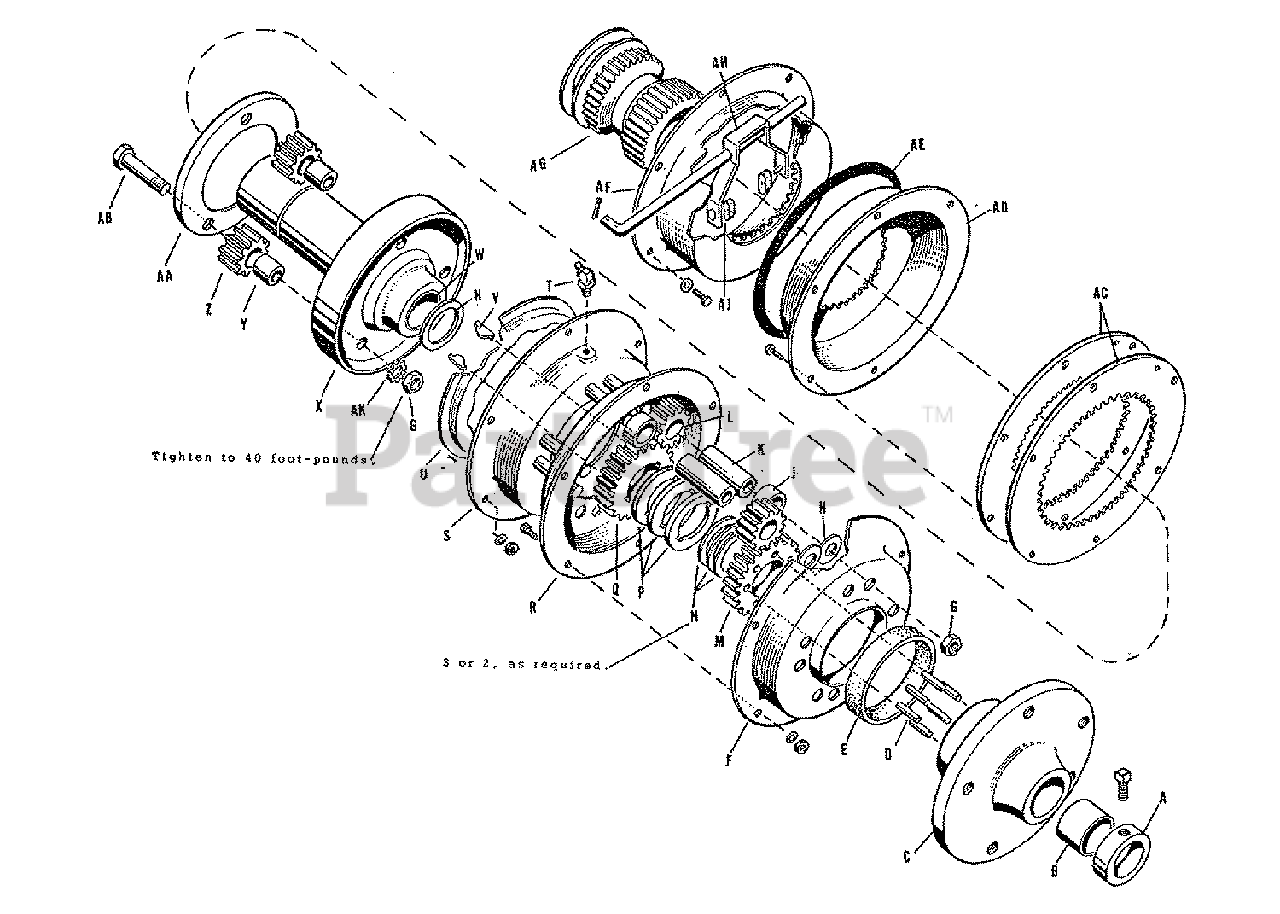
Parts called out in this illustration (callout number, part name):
A	COLLAR, Set
C	HUB, Wheel, R.H.
D	PIN, Roll
E	SEAL, Differential Cover
F	COVER, Differential
G	NUT, Lock, Full Hex, 3/8-24
H	WASHER, Plain, 5/16"
J	SPACER, Differential
K	SPINDLE, Pinion, Differential
L	PINION, Differential
M	GEAR, Differential
P	WASHER, Axle
Q	GEAR, Differential
R	COVER, Differential
S	CARRIER ASSEMBLY
T	FITTING, Grease, Alemite #1637
U	PLATE, Thrust
V	KEY, Hi-Pro, HP-608
X	SPIDER ASSEMBLY
Y	SPACER, Pinion
AA	RING, Bolt
AB	BOLT, Hex Head
AC	GEAR, Ring
AD	COVER ASSEMBLY
AE	SEAL, Housing Assembly
AF	HOUSING ASSEMBLY
AG	GEAR ASSEMBLY, Sun
AH	CLEVIS ASSEMBLY
AJ	BLOCK, Shift
AK	LOCKWASHER, External Shakeproof
